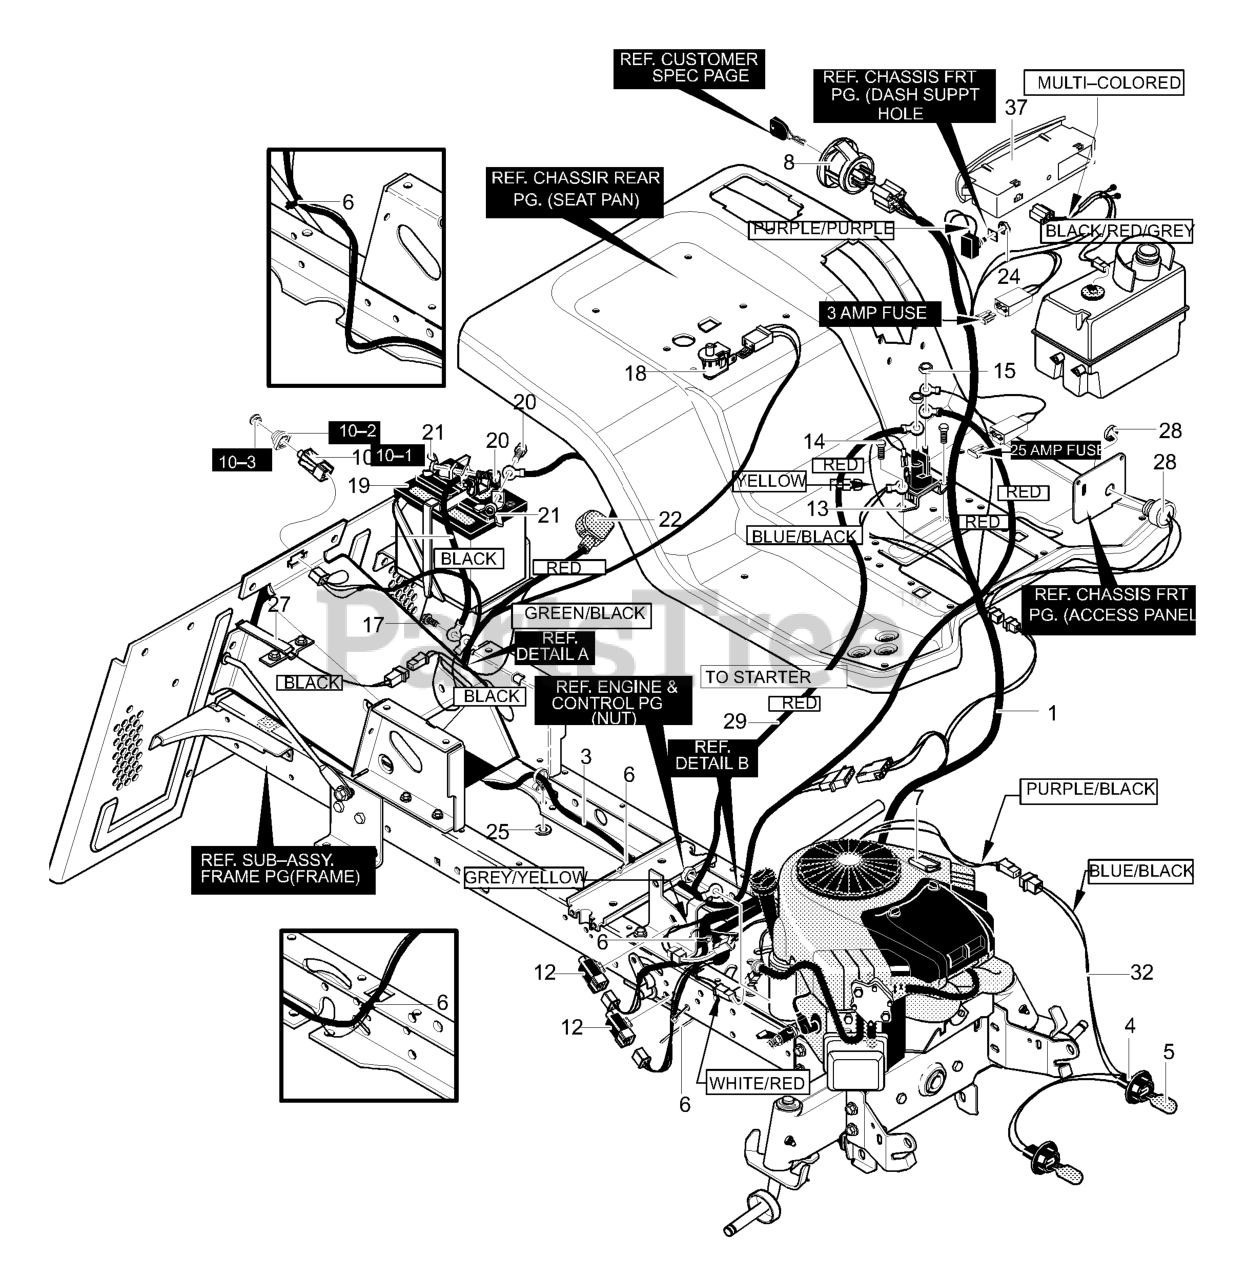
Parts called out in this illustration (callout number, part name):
1	Wire Harness
3	Rear Harness
4	Socket, Lamp
5	Bulb, Light
6	Cable Tie
7	Wire Clip, Adhesive
8	Switch, Ignition
10	ASSEMBLY, Switch Double Pole Delta
10-1	Switch, Double
10-2	Boot, Switch
10-3	Switch Cap
12	Switch, Limit
13	Solenoid
14	SCREW 1/4x.50
15	NUT, 1/4-20
16	Ground Wire
17	SCREW, 1/4x.50
18	Seat Switch
19	Battery 6 Plate
20	BOLT, 1/4-20x.63
21	Wing Nut
22	Boot, Battery
24	NUT, Plastic
25	WASHER, Flat
27	Tape Switch
28	Buzzer, For Bag Full
29	Wire, Lead Solenoid to Starter
32	Wire Harness Headlights
37	Elect. Diagnostic
